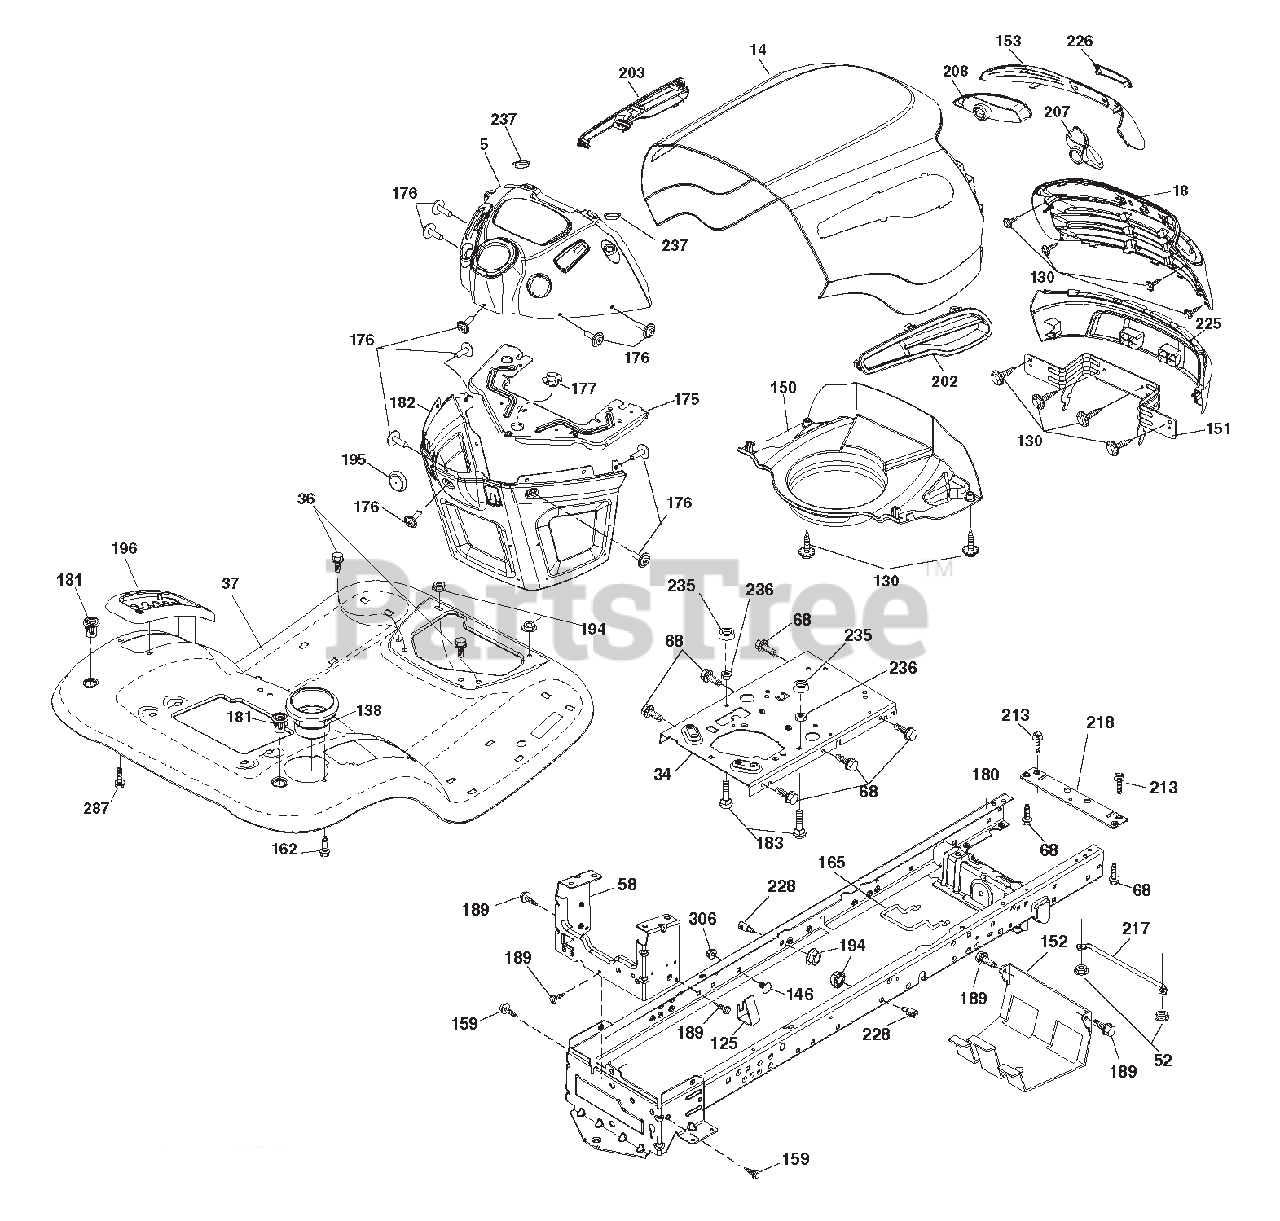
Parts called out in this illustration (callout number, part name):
5	DASH.P/L.TEX.CABLE
18	GRILLE.ELITE.ARIENS.BLACK
34	PLATE.ENGINE.WELDED.CHASSIS
36	SCREW.5/16-18X3/4.SMGML.TAP/R
52	Nut, Hex, Crownlock 5/16-18
58	DRAWBAR.UPPER.2PC.SML.FENDER
68	SCREW.THDROL.5/16-18 X 1/2TYTT
125	CLIP.FUEL.LINE
138	CUPHOLDER TL TEX 428
150	AIR DUCT
151	BRACKET.PIVOT
152	SHIELD.BROWNING.W/TEX
153	LENS.BAR
159	SCREW.HEXWSH THDR3/8-16X3/4.BL
162	SCREW.HEX.WSH.HI-LO.1/4X1/2UNC
165	SUPPORT.TANK.REAR.W/TEX
175	CROSSMEMBER.LT
176	SCREW.#10-24X5/8.RND.QUDRX.GIM
177	BUSHING.STEERING.YT/GT
180	CHASS.WLDMT.TL.12GA/2PC.18/22"
181	BUSHING MNT FEND CRGO BLK TEX
182	DASH.LOWER.LT.CCS
183	BOLT.FIN.HEX.5/16-18 UNC X1-1/
189	SCREW.5/16-18X3/4.SMGML.TAP/BL
194	Nut, Lock Hex Flange 5/16-18 u
195	PLUG HOLE DASH TOWER
196	CONSLE.ASM.DECK.LFT.BL/RBT.TLT
202	VENT RH
203	VENT.SIDE.LH
207	BEZEL.RH
208	BEZEL.LH
213	BOLT.HEX.HD.1/4-20UNC X 3/4
217	ROD.PIVOT.HOOD
218	X-PIECE.HOOD.STOP.NON/STEALTH
226	ARIENS.LOGO.PLATE
228	STUD.FASTNER.W/'D'ANTI-ROTATIO
235	SPACER.FENDER
236	NUT.CENTER LOCK.5/16-18 UNC
237	PLUG.MOUNT.CARGO
287	SCREW.HEX.WASHEAD.1/4-20 X 3/8
306	Nut, Hex, Flangelock 3/8-16
